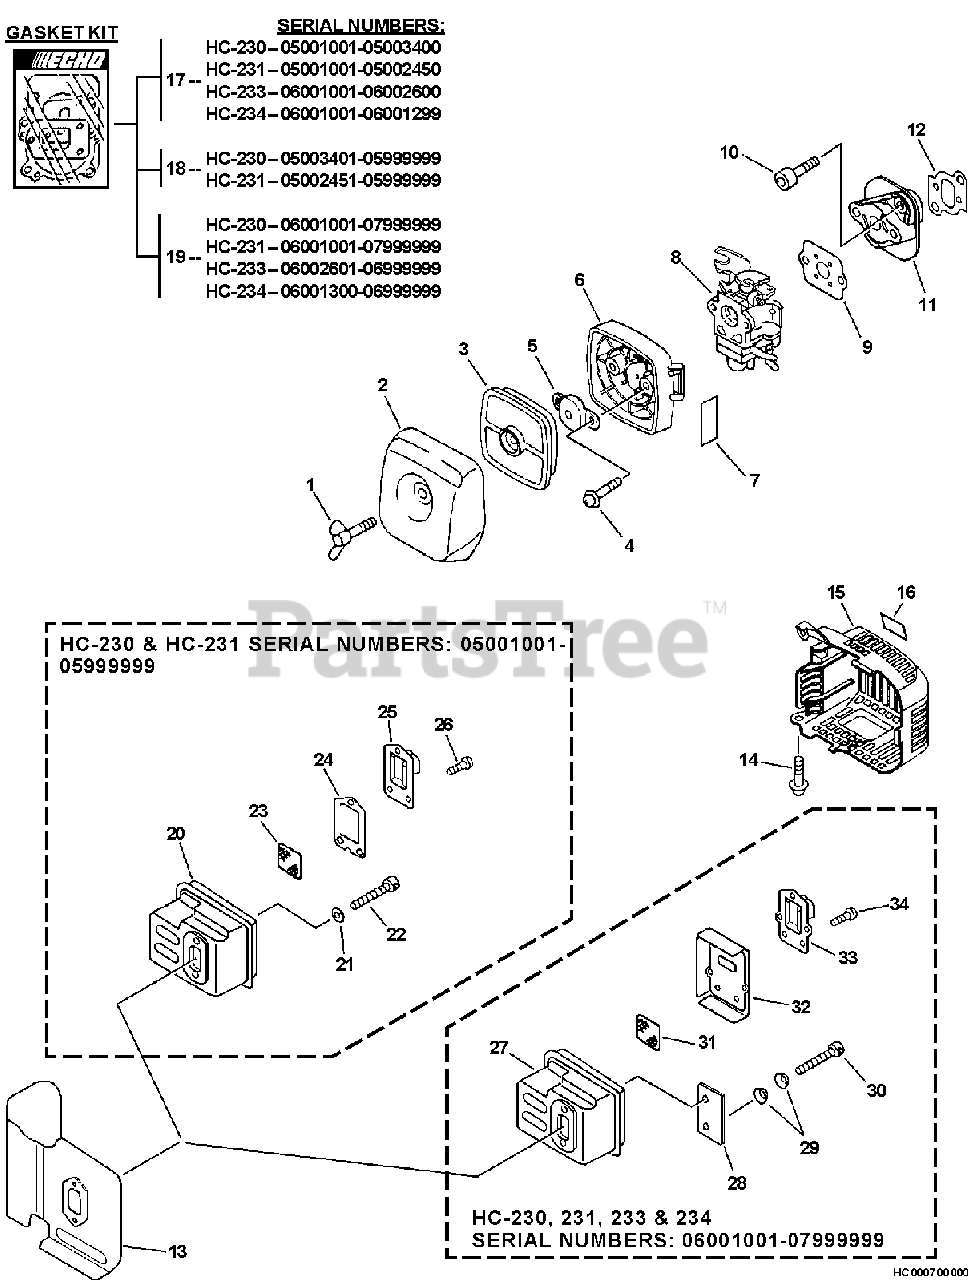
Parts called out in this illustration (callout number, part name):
1	BOLT, WING 5×20
2	COVER, AIR FILTER - GRAY
3	FILTER, AIR - SINGLE LAYER
4	SCREW 5×60
5	PLATE, PREVENT
6	CASE, AIR FILTER - GRAY
7	LABEL, CHOKE
8	CARBURETOR - WYJ-314
9	GASKET, INTAKE
10	BOLT 5×25
11	INSULATOR, INTAKE
12	GASKET, INTAKE
13	HEAT SHIELD, EXHAUST
14	BOLT 5×12
15	COVER, EXHAUST
16	LABEL, CAUTION - HOT
17	GASKET KIT
18	GASKET KIT
19	GASKET KIT
21	WASHER, FLAT 5.5×10×0.8
22	BOLT 5×55
23	SCREEN, SPARK ARRESTER
24	GASKET, EXHAUST
25	GUIDE, EXHAUST
26	SCREW 4×10
27	MUFFLER
28	PLATE, EYE
29	CONICAL WASHER
30	BOLT 5×55
31	SCREEN, SPARK ARRESTER
32	GASKET, EXHAUST
33	GUIDE, EXHAUST
34	SCREW 4×10
